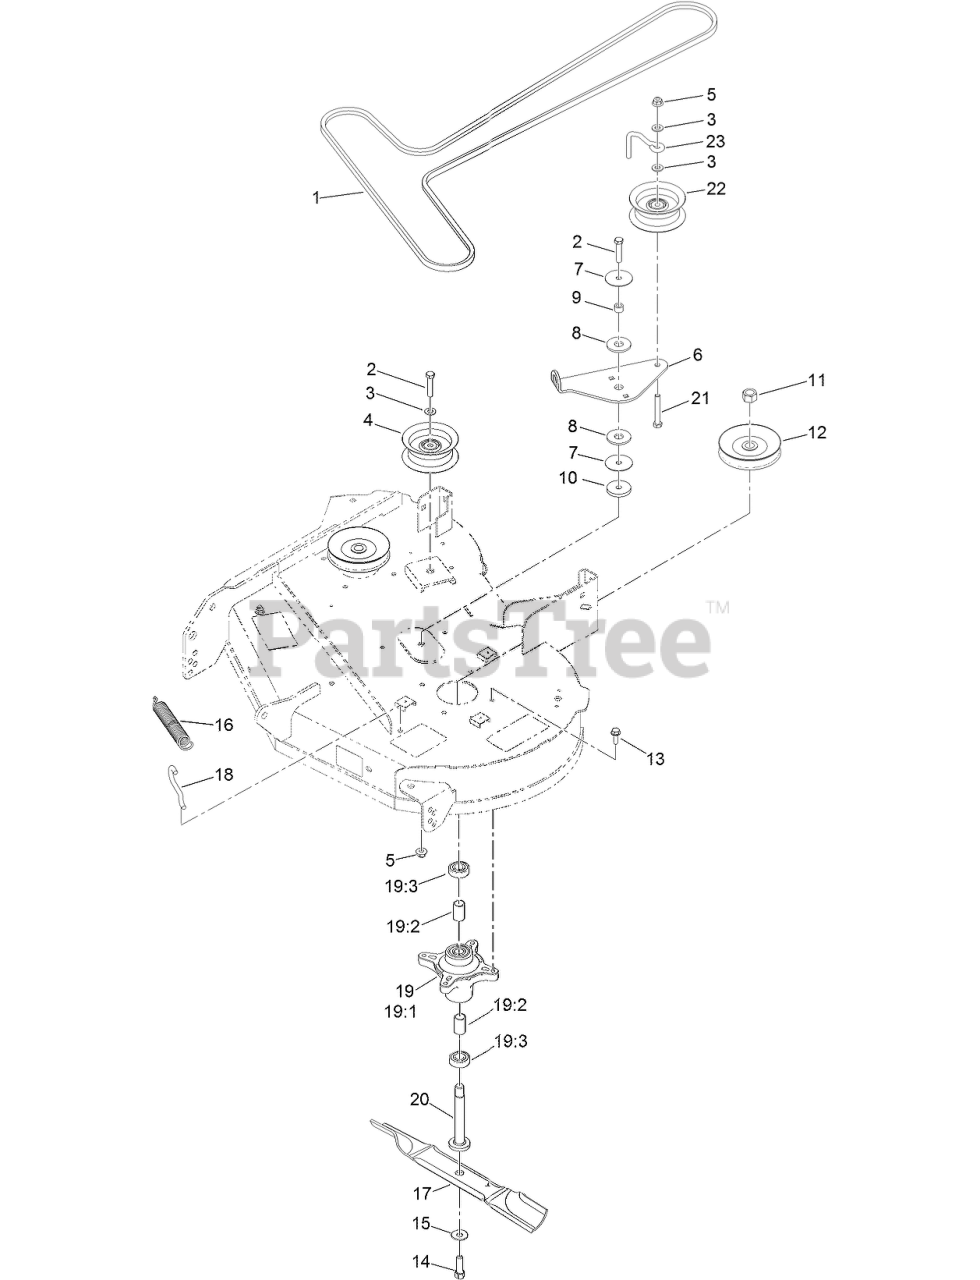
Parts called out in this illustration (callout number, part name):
1	BELT-V
2	SCREW-HH
3	WASHER-FLAT
4	PULLEY-IDLER, FLAT
5	NUT-HF, NI
6	ARM-IDLER
7	WASHER
8	WASHER-FRICTION, COMPOSITE
9	SPACER
10	WASHER-PLAIN
11	NUT-HEX
12	PULLEY ASM
13	SCREW-TAPTITE
14	SCREW-HH
15	WASHER-BELLEVILLE
16	SPRING-EXTENSION
17	BLADE-HI LIFT
18	HOOK-RETURN, SPRING
19	SPINDLE ASM
19:1	SPINDLE
19:2	SPACER
19:3	BEARING-BALL
20	SHAFT-SPINDLE
21	SCREW-HH
22	PULLEY-IDLER, FLAT
23	GUIDE-IDLER, BELT
